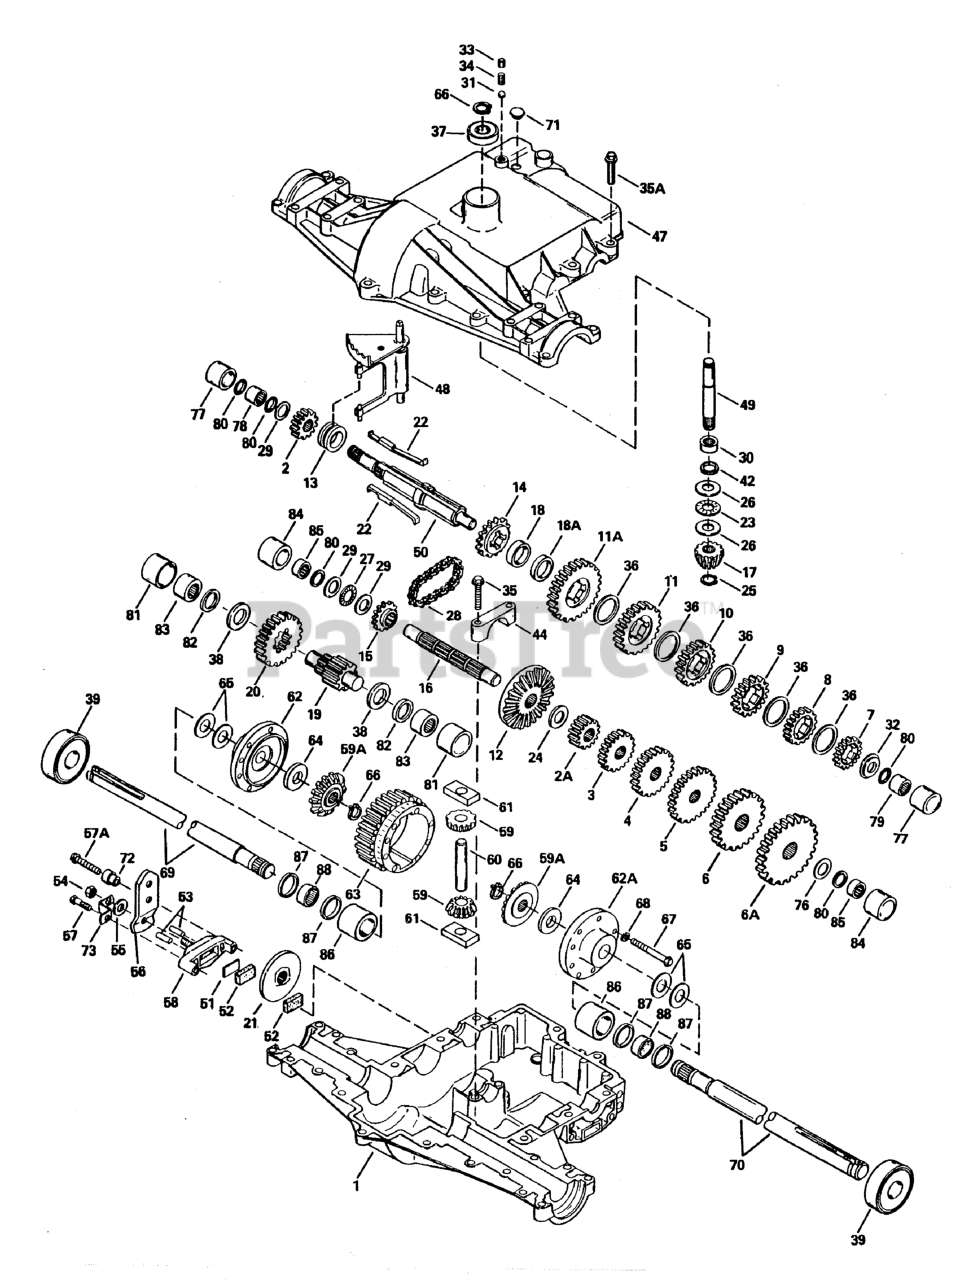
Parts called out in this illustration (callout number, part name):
1	Case, Transaxle
2	Gear, Spur (15 Tooth)
2A	Gear, Spur (15 Tooth)
3	Gear, Spur (18 Tooth)
4	Gear, Spur (20 Tooth)
5	Gear, Spur (23 Tooth)
6	Gear, Spur (25 Tooth)
6A	Gear, Spur (28 Tooth)
7	Gear, Spur (22 Tooth)
8	Gear, Spur (25 Tooth)
9	Gear, Spur (27 Tooth)
10	Gear, Spur (30 Tooth)
11	Gear, Spur (32 Tooth)
11A	Gear, Spur (35 Tooth)
12	Gear, Bevel (33 Tooth)
13	Collar, Shirt
14	Sprocket (18 Tooth)
15	Sprocket (9 Tooth)
16	Shaft, Counter
17	Bevel Pinion, Input (13 Tooth)
18	Spacer, Neutral (.276/.268 Thick)
18A	Spacer, Neutral (.350/.340 Thick)
19	Shaft, Output (9 Tooth)
20	Gear, Output (35 Tooth)
21	Disk, Brake
23	Bearing, Thrust
24	WASHER, Thrust
25	Ring, Retaining
26	Race, Thrust
27	Bearing, Thrust
28	Chain, Roller (No. 41 Chain, 24 Links)
29	WASHER, Thrust
30	Bearing, Needle
31	Ball, Steel
32	WASHER, Thrust
33	Screw, Set, 3/8-16 x 3/8
35	Screw, Flanged Hex Head Threadforming, 1/4-20 x 1-1/4
35A	Screw, Hex Head Threadforming, 5/16-18 x 1-1/4
36	WASHER, Thrust
37	Bearing, Ball
38	WASHER, Thrust
39	Bearing, Ball
42	Seal, Oil
44	Cap, Bearing
47	Cover, Transaxle
48	Rod & Fork Assembly, Shift
49	Shaft, Input
50	Shaft, Brake
51	Plate, Brake Pad
52	Pad, Brake
53	Pin, Dowel
54	Locknut, 5/16-24
55	WASHER, Flat
56	Lever, Brake
57	Screw, Flanged Hex head Threadforming, 1/4-20 x 1-1/4
57A	Screw, Flanged Hex Head Threadforming, 1-4/20 x 2-1/4
58	Holder, Brake Pad
59	Pinion, Differential Bevel
59A	Gear, Bevel
60	Pin, Drive
61	Block, Drive
62	Carrier, Differential (Threaded Holes)
62A	Carrier, Differential
63	Gear, Ring (31 Tooth)
65	WASHER, Thrust
66	Ring, Snap
67	Screw, Hex Head, 1/4-20 x 2-1/4
68	Lockwasher, 1/4"
69	Axle (12-1/4" Long)
70	Axle (26-1/4" Long)
71	Plug, hex Head, 9/16-18 Thread
73	Bracket, Brake Lever
78	Bearing, Needle
79	Bearing, Needle (capped)
82	Ring, Square Cut
83	Bearing, Needle (capped)
85	Bearing, Needle (capped)
87	Ring, Square Cut
88	Bearing, Needle
